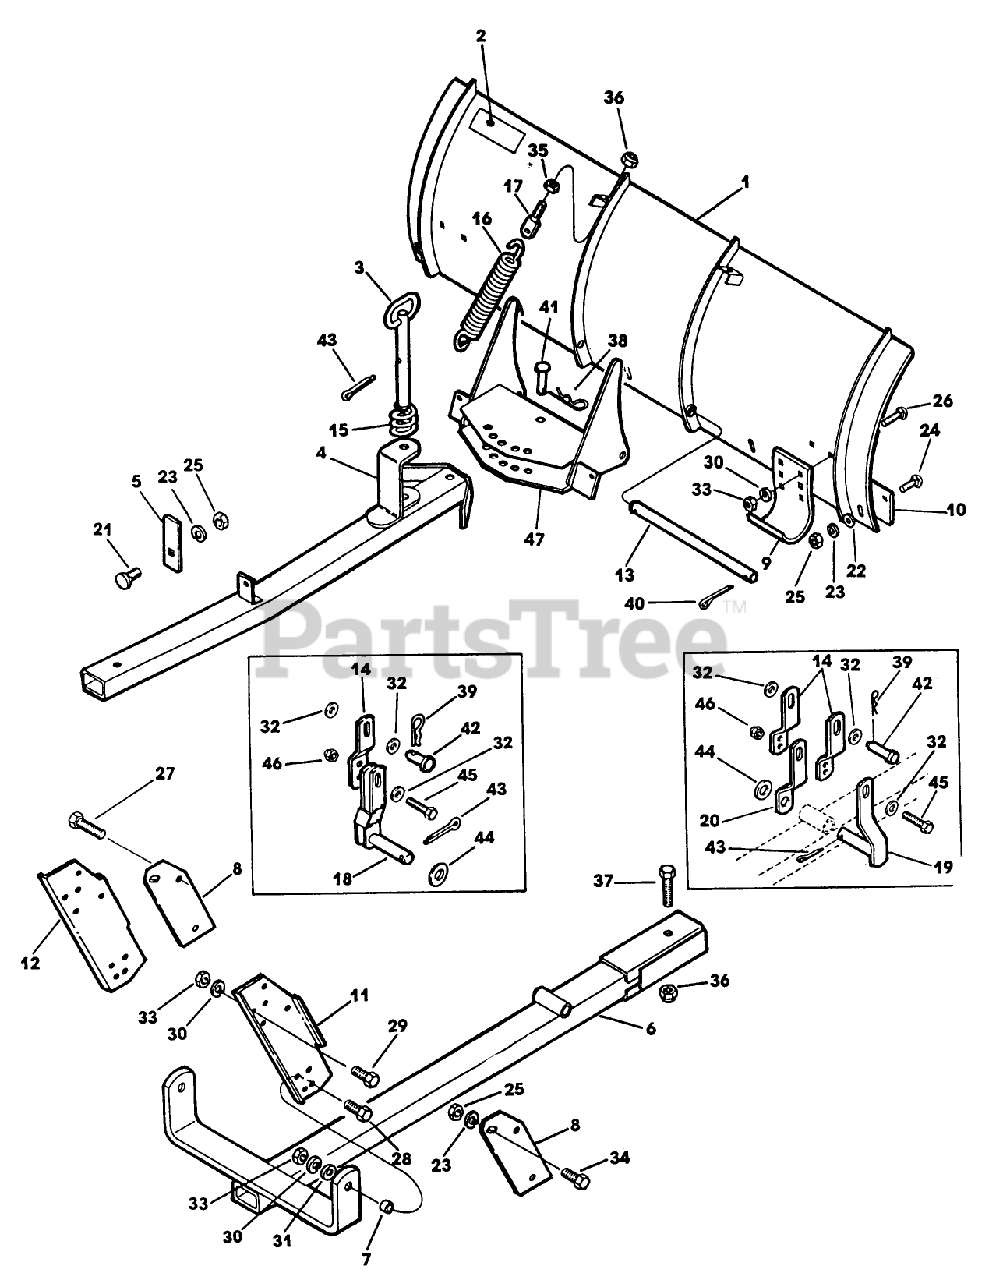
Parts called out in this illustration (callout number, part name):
6	FRAME AY-REAR
7	SPACER
10	BLADE SCRAPPER
12	BRACKET MOUNTING
18	LINK AY-LIFT
25	NUT SS
30	WASHER
31	WASHER
33	NUT
34	SCREW
36	NUT-HEX CONE LOK
39	PIN - SPRING CLIP
41	PIN-CLEVIS
42	PIN-CLEVIS
46	NUT-HEX
